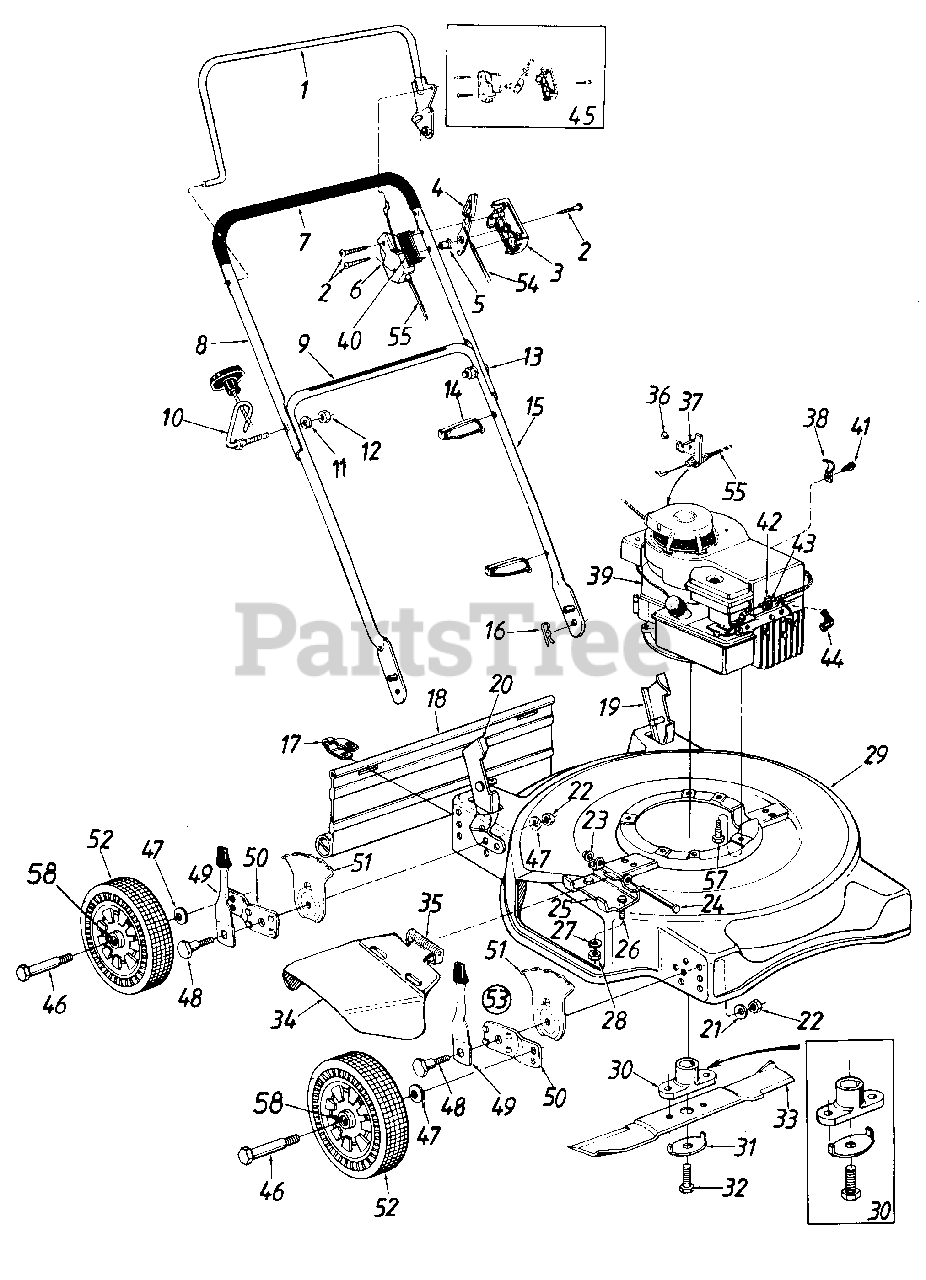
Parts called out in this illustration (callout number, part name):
1	Control Handle Ass'y.
2	Truss Mach. Scr. #12 x 1.5" Lg.
3	Control Panel Half
4	Throttle Control Lever
5	Control Disc Pin
6	Clutch Panel Half
7	Grip
8	Upper Handle
9	Instruction Label-Handle
10	Rope Guide Bolt
11	L-Wash. 5/16" I.D.
12	Hex Nut 5/16-18 Thd.
13	Curved Carriage Bolt 5/16-18 -x 1.38" Lg.
14	Cable Tie
15	Lower Handle
16	Hairpin Cotter
17	Hinge Clip
18	Rear Flap
19	Handle Bracket Ass'y.-L.H.
20	Handle Bracket Ass'y.-R.H.
21	Bell-Wash. .39" I.D. x 1.38"
22	Hex Nut 3/8-16 Thd.
23	Push Cap 1/4" Rod
25	Aaapter Plate
26	Hex Bolt 1/4-20 x .50" Lg.
27	L-Wash. 1/4" I.D.
28	Hex Nut 1/4-20 Thd.
31	Blade Bell-Wash. .45" I.D. x 2.38"
32	Hex Bolt 3/8-24 x 1.5" Lg.
33	20" Blade
34	Chute Deflector Ass'y.
35	Torsion Spring
37	Cable Bracket
38	Cable Clamp
39	Engine
40	Control Label-Throttle
41	Hex B-Tap Scr. #10 x .38"
43	Hex AB-Tap Scr. #8 x .38" Lg.
44	Spark Plug Boot
45	Kit-Control Housing Comp.
47	Bell-Wash. .400" I.D. x .88"
48	Shld. Bolt .50" Dia. x .357"
49	Spring Lever Ass'y. w/Knob
50	Pivot Bar
51	Height Adj. Plate
52	Wheel Ass'y. (8 x 1.75)
53	Height Adj. Ass'y. Comp.- 0 R.H.
54	Throttle Cable-51"
55	Control Cable-39"
57	Hex L-Wash. Hd. Scr. 3/8-16 x 1.0" Lg.
58	1/2" I.D. Ball Bearing
